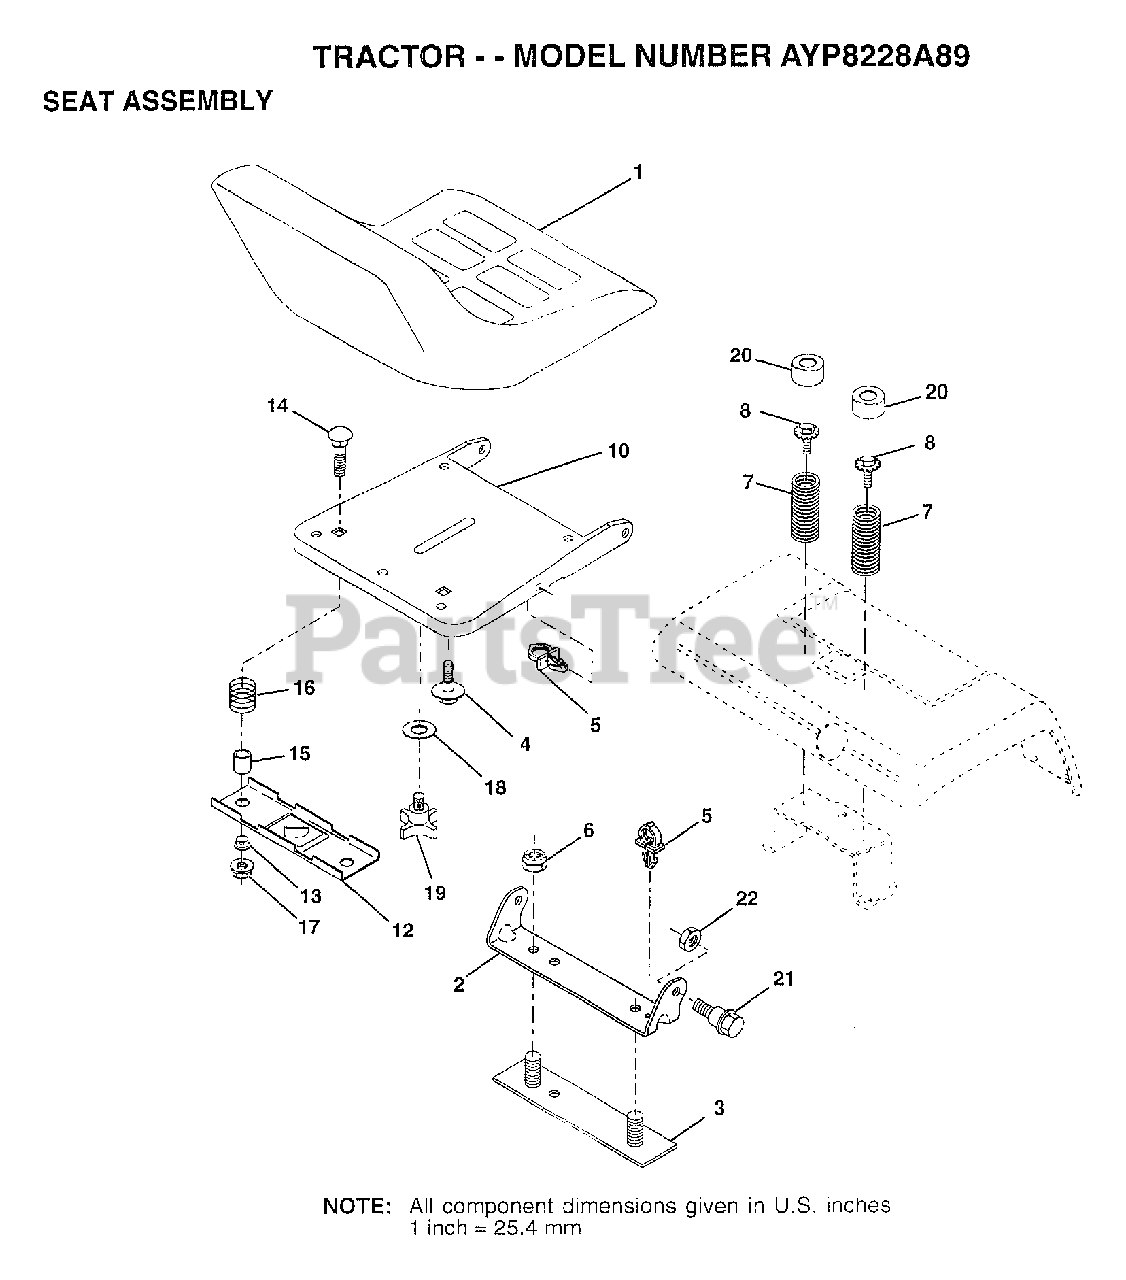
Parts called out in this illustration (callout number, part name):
2	BRACKET PVT SEAT
3	STRAP ASM FENDER
4	"BOLT,SHOULDER"
5	CLIP.PUSH-IN.HING
6	NUT
7	SPRING COMPRESSIO
8	BOLT.5/16-18.UNC
10	PAN-SEAT
12	BRKT SWITCH
13	BUSHING
14	BOLT-RD HD SQ NK
15	SPACER SPLIT
16	SPRING COMPRESSED
18	WASHER
19	"KNOB 1/2"" YT"
20	CAP SPRING
21	"BOLT,SHOULDER"
